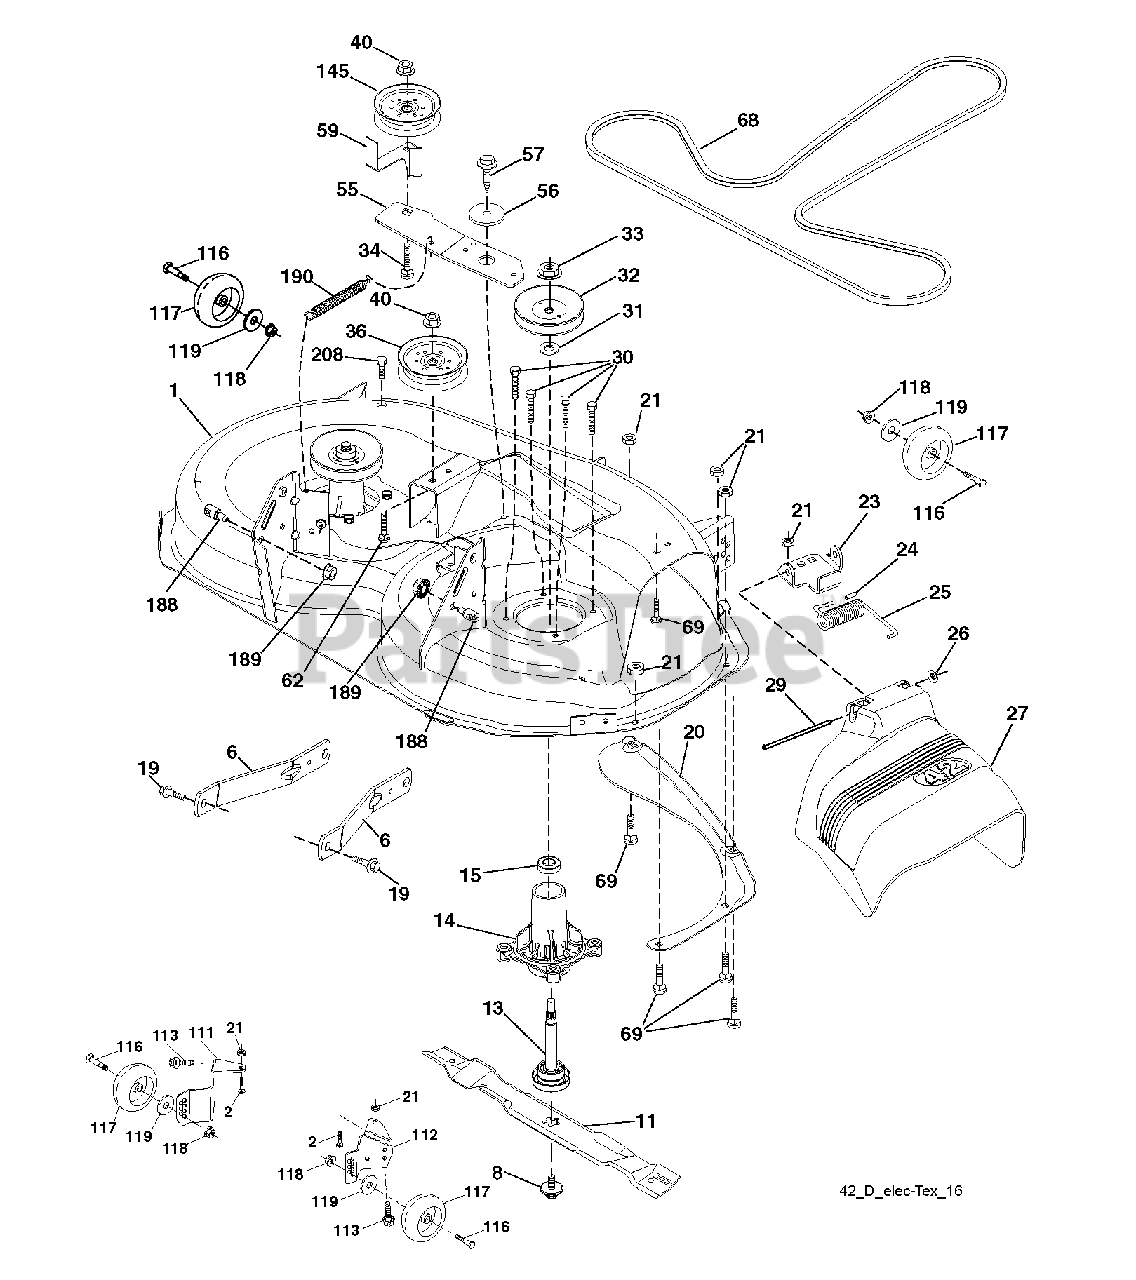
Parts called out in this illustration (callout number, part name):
1	DECK.WELDMNT.42"GREYMS498
2	BOLT 5/16-18 X3/4 ZN/YEL GR 5
6	ARM.SUSPENSION.MOWER.R
8	BOLT.WASHER.ASM.7/16-2
11	42" HI-LIFT BLADE
13	SHAFT.ASM.MDRL.N/GREASE.38
14	HOUSING.MANDREL.4PT.
19	BOLT.SHOULDER
20	BAFFLE.VORTEX
21	LOCKNUT
23	BRKT.DEFLECTOR.38"2005+
24	CAP-SLEEVE LT
25	SPRING.TORSION.DEFLECT
26	NUT PUSH M
27	SHIELD.DEFLECTOR.MOWER.42"BLAC
29	ROD.HINGE
30	SCREW, WASHER HEAD
31	WASHER.SPACER.MANDREL
32	PULLEY/MANDREL
33	NUT.FLANGE.LOCK.TOP
34	BOLT.3/8-16X1.50
36	PULLEY.IDLER.2006
40	NUT LOCK FLG 3/8-16 UNC
55	IDLER.ARM.42"
56	SPACER.RETAINER
57	SCREW 3/8-16X1
59	GUARD, BELT
68	BELT V SECONDARY
69	BOLT
111	BRKT.WHEEL.GAUGE.LH.42"
112	BRKT.WHEEL.GAUGE.RH.42"
113	BOLT.5/16HEX.WHS.HD
116	BOLT M
117	WHEEL.GAGE.HALF.SPOKED
118	LOCKNUT
119	WASHER
145	PULLEY.IDLER.48"PRIMARY
188	STUD.FASTNER.W/ANTI-ROTATE
189	NUT LOCK HEX FLANGE 5/16-18
190	SPRING.MOWER.DRIVE.ELECTRIC
208	SCREW 3/8-16X1/2
